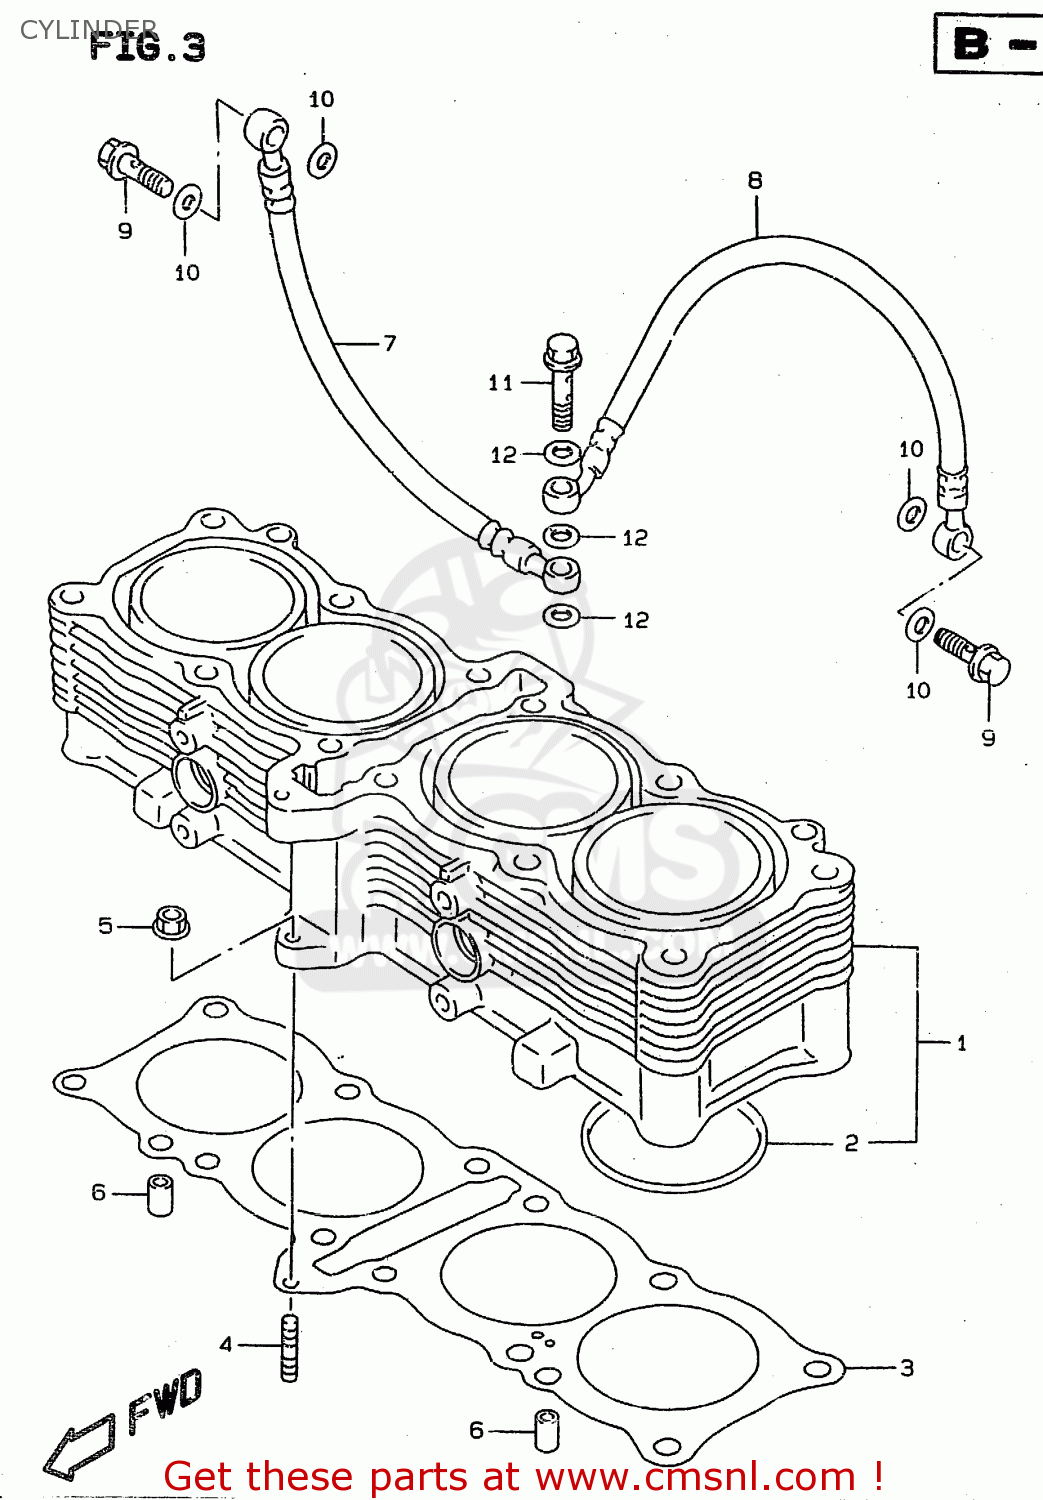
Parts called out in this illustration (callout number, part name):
1	CYLINDER COMP
2	O RING(D:2.6,ID:69.6)
3	GASKET,CYLINDER
4	STUD,M6X1X32
5	NUT
6	PIN
7	HOSE,CYLINDER HEAD OIL,R
8	HOSE,CYLINDER HEAD OIL,L
9	BOLT,OIL PIPE UNION,NO
10	GASKET(8.2X14X1) (NAS)
11	BOLT,OIL PIPE UNION,NO
12	WASHER(10X15X1.5)
